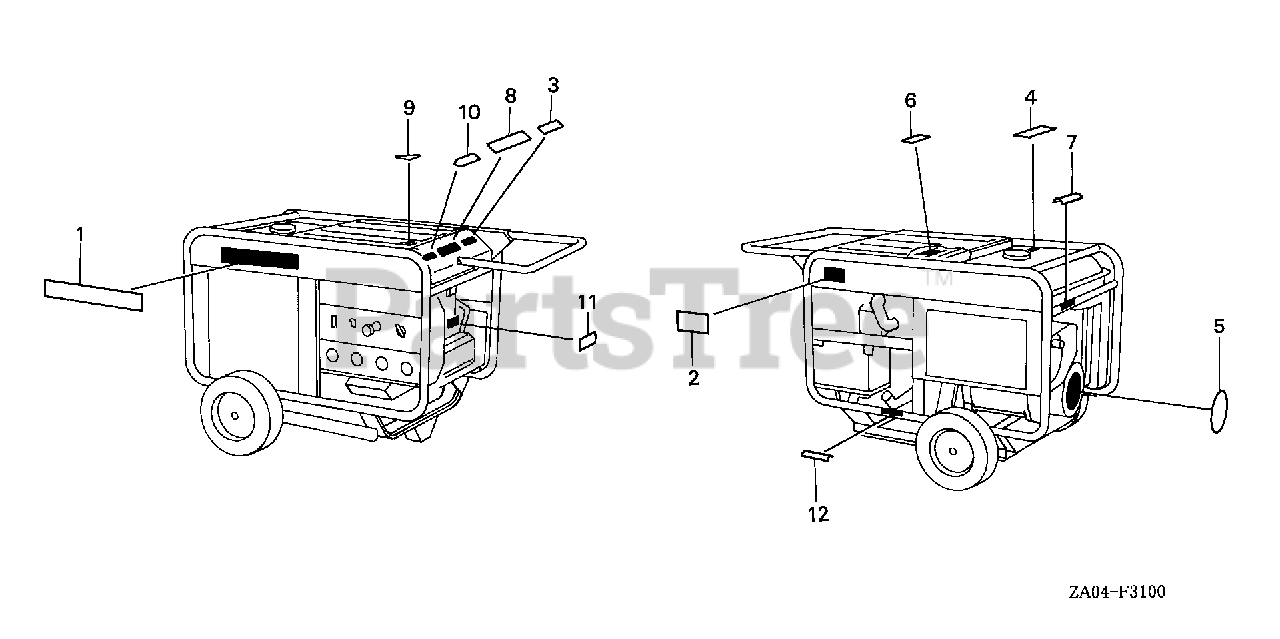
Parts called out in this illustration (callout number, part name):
1	EMBLEM
2	MARK, SPECIFICATION
3	LABEL, RAIN WARNING (ENGLISH)
4	MARK, CAUTION (ENGLISH/FRENCH)(SPANISH)
6	MARK, AIR CLEANER ARROW
7	MARK, EX. CAUTION (ENGLISH/FRENCH)
7	MARK, EX. CAUTION
8	MARK, CAUTION
9	LABEL, OPERATOR WARNING
10	LABEL, CONNECT WARNING (ENGLISH)
12	MARK, OIL CAUTION
